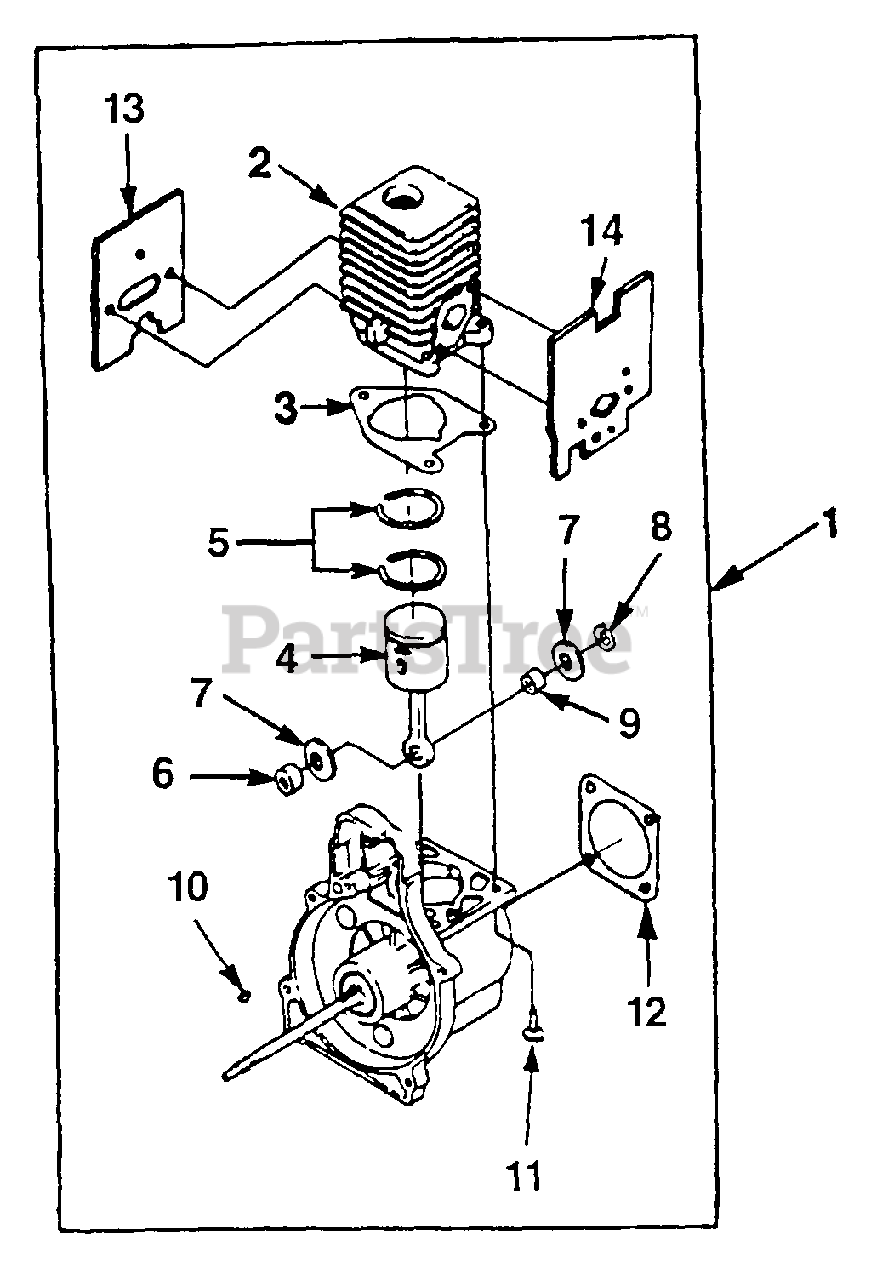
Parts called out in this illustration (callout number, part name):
1	SHORT BLOCK
2	CYLINDER & GASKET
3	GASKET-Cylinder
4	PISTON & ROD
5	RING-Piston
6	SPACER-Bearing
7	WASHER-Thrust
8	RING-Retaining
9	BEARING-Needle
10	KEY-Woodruff
11	SCREW-Machine Pan Hd (12-24 X 3/4")
12	GASKET-Crankcase
13	GASKET-Muffler
14	GASKET-Heat Dam
